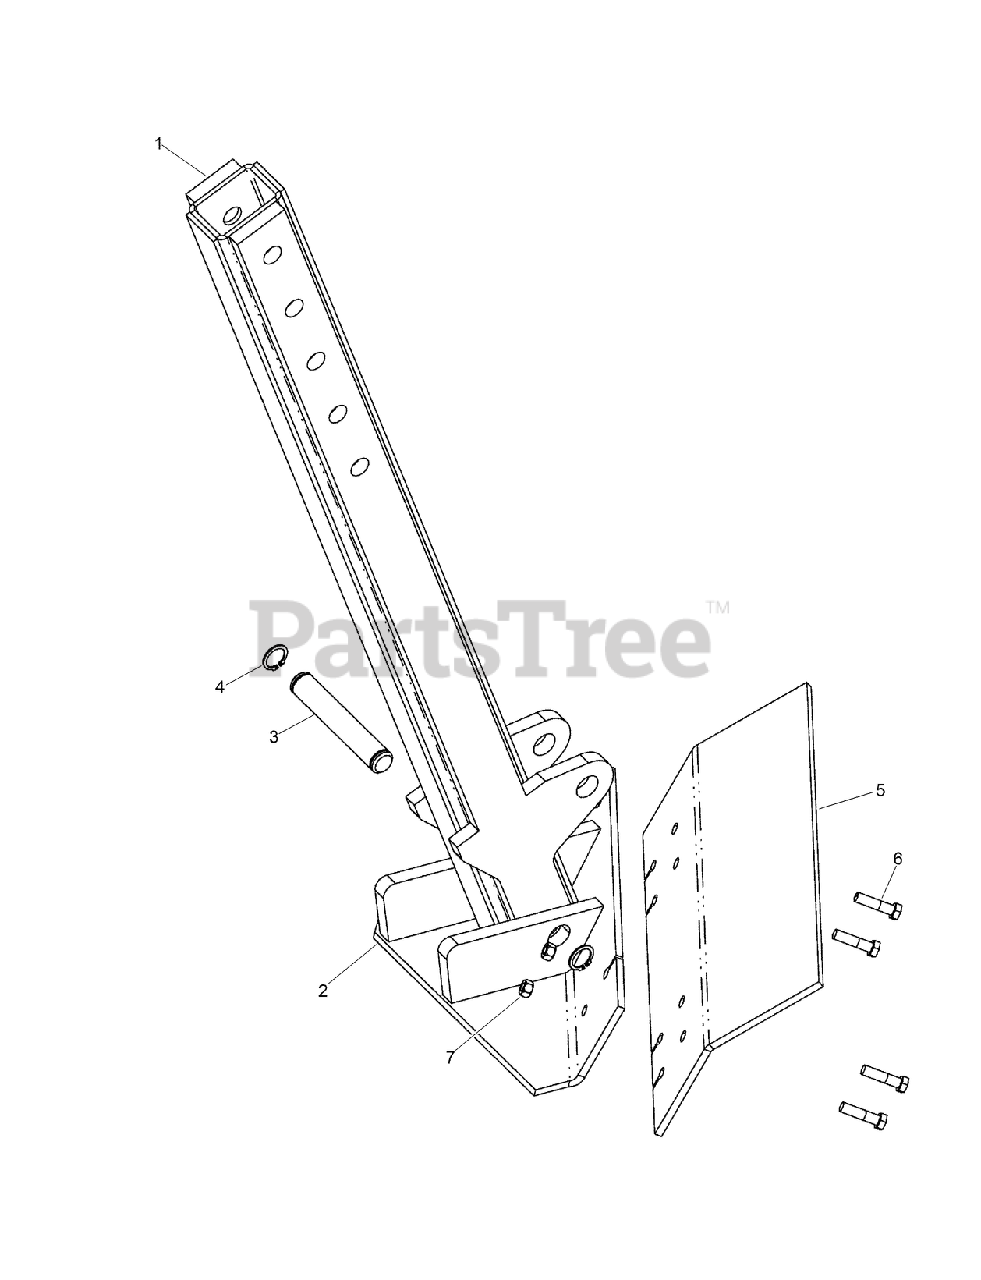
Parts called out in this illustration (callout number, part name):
1	WELDMENT - Stabilizer Bar
2	WELDMENT - Foot, Right-Hand
3	PIN-PIVOT
4	RING-RETAINING
5	PLATE - Berm Scraper
7	NUT-LOCK, HEX
